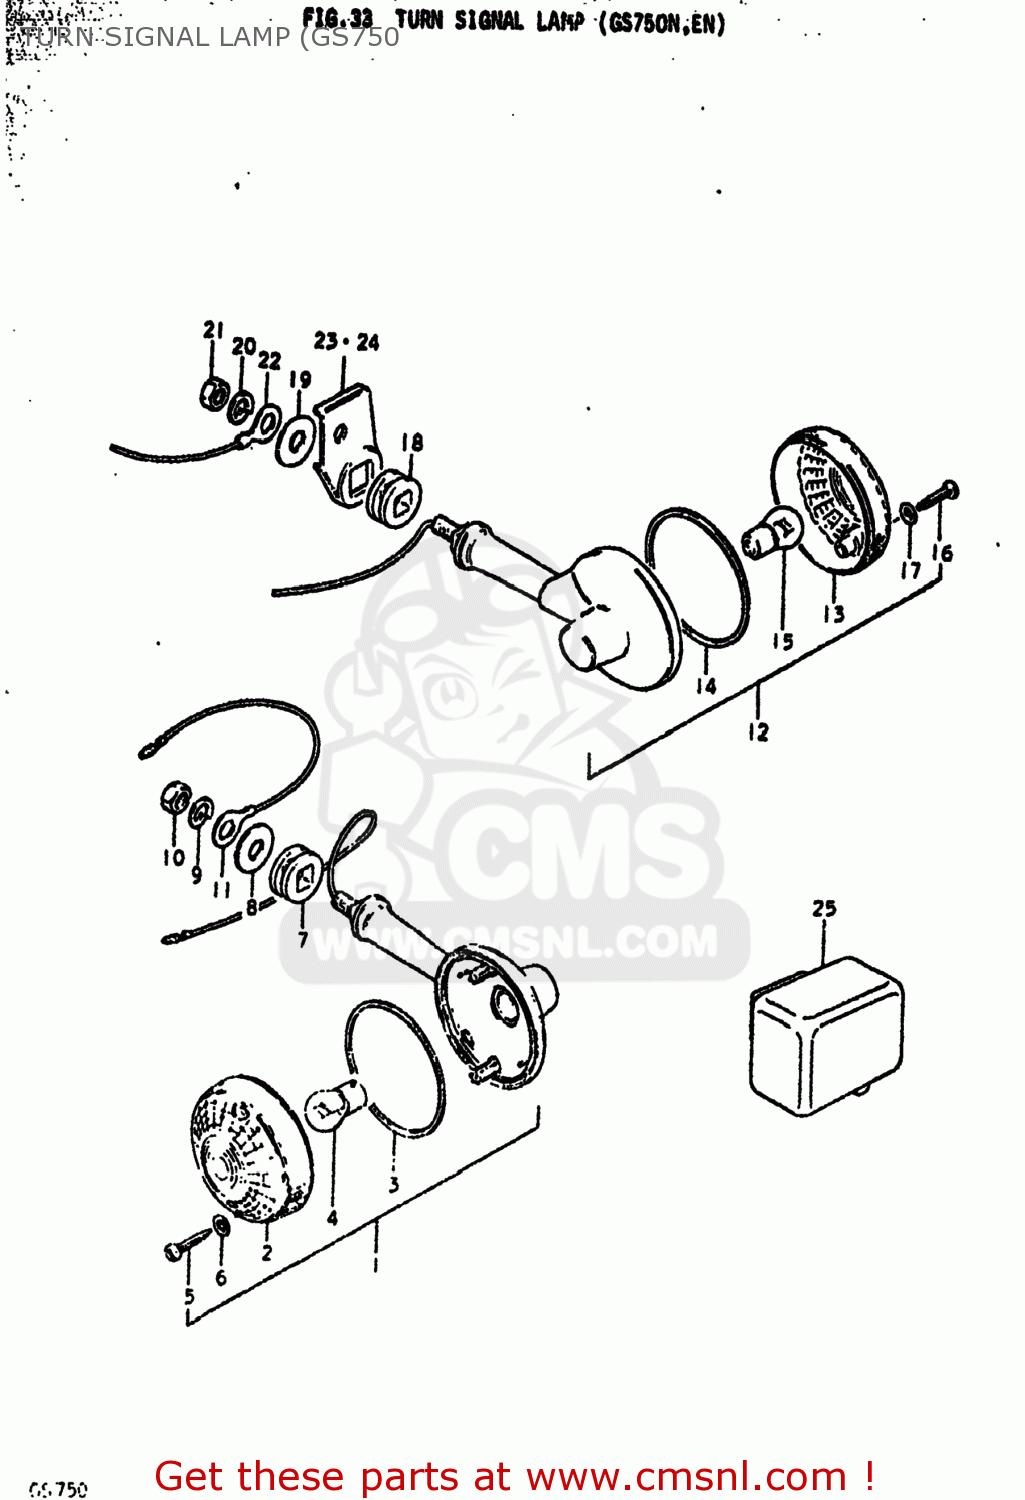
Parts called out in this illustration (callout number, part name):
1	LAMP ASSEMBLY,FRONT TURN SIGNAL
2	LENS
3	GASKET (NAS)
4	BULB(12V23W,STANLEY,A4577A)
5	BOLT
6	GASKET (NAS)
7	CUSHION
8	WASHER
9	LOCK WASHER
10	NUT
11	WIRE
12	LAMP ASSEMBLY,FRONT TURN SIGNAL
13	LENS
14	GASKET (NAS)
15	BULB(12V23W,STANLEY,A4577A)
16	BOLT
17	GASKET (NAS)
18	CUSHION
19	WASHER
20	LOCK WASHER
21	NUT
22	WIRE
23	BRACKET,RR TURNSIGNAL LAMP,R
24	BRACKET,RR TURNSIGNAL LAMP,L
25	RELAY,TURN SIGNAL
